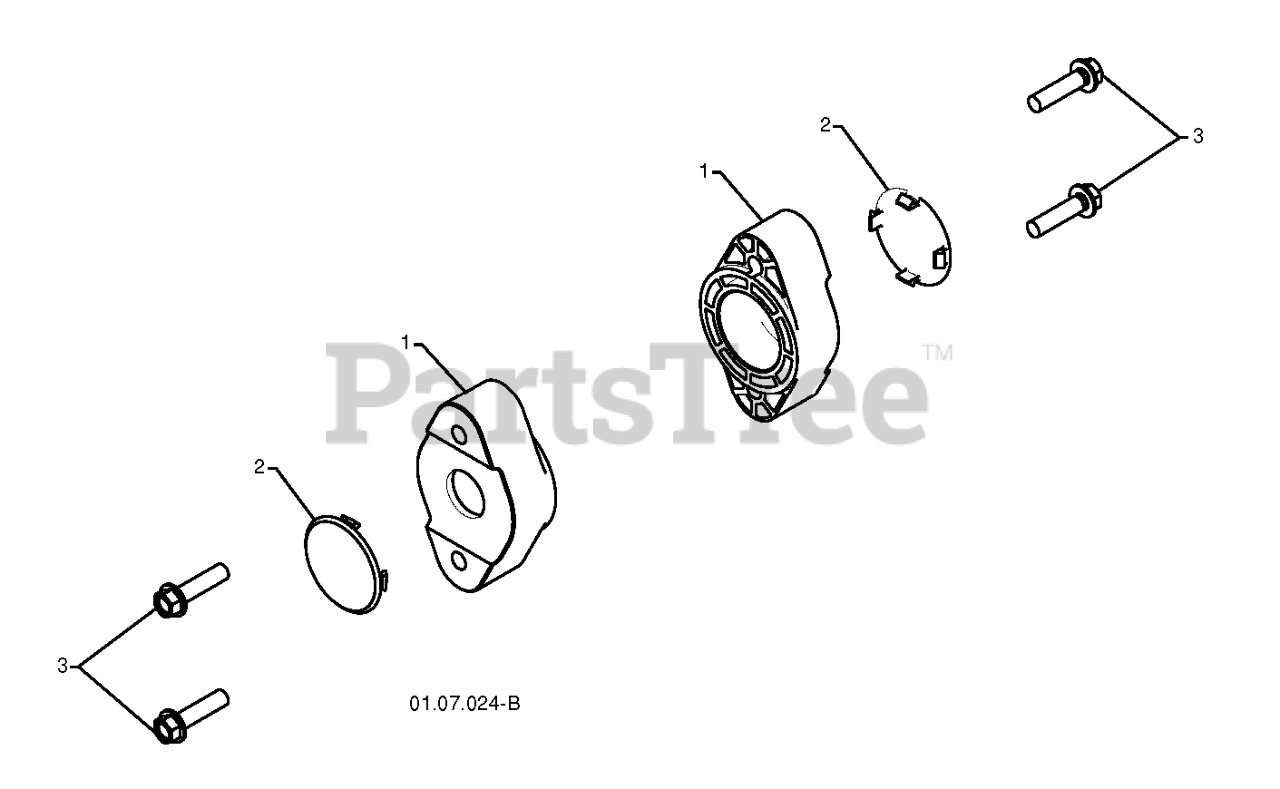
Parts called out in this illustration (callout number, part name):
1	BEARING.AUGER.SHAFT
2	PLUG.BEARING.HOLE.HSG
3	SCREW, HEX HD 5/16X1
